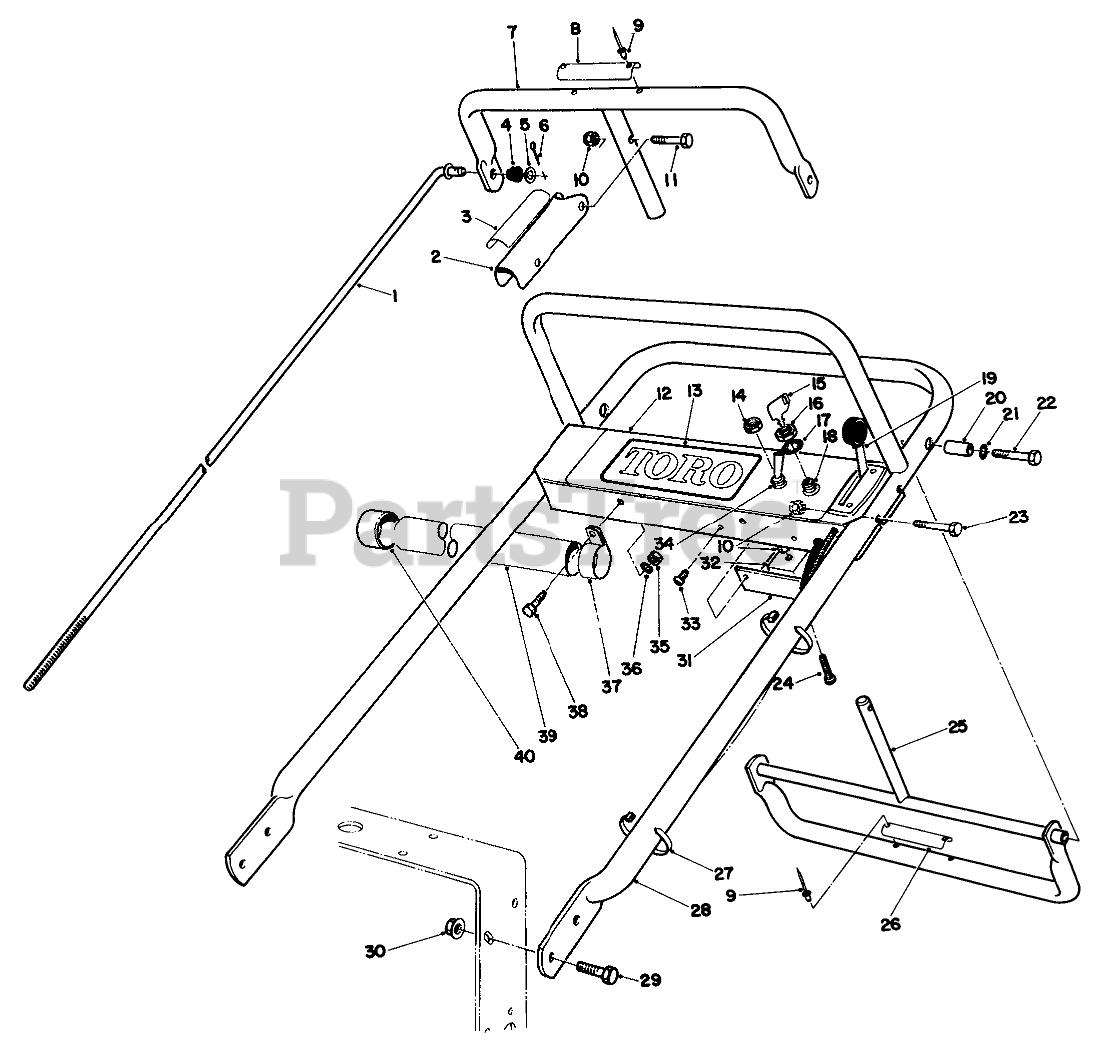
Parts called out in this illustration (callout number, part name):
1	ROD-CONTROL
2	Lever-Parking Brake
3	DECAL-LEVER, PARKING
4	GROMMET-RUBBER
5	WASHER-PLAIN
6	PIN-COTTER
7	Bar-Control
8	DECAL-CONTROL BAR
9	RIVET-BLIND
10	NUT-LOCK, NI
11	SCREW-SHH
12	Panel-Control
13	DECAL-CONTROL PANEL
14	NUT
15	KEY-IGNITION
16	NUT-HH
17	WASHER-TOOTH, INTERNAL
18	Switch (Incl. Ref. #16 & 17)
19	THROTTLE-CONTROL
20	PIVOT-SPACER
21	WASHER-LOCK
22	SCREW-HH
23	SCREW-SHH
24	SCREW-HWH
25	Control-Pivot
26	DECAL-REVERSE HANDLE
27	TIE-CABLE
28	HANDLE-UPPER
29	SCREW-HHF
30	NUT-HF
31	PANEL-BOTTOM
32	RECTIFIER-BRIDGE
33	SCREW-HWHTF
34	Switch-Clutch (Incl. Ref. #14)
35	NUT-LOCK, NI
36	WASHER-FLAT
37	CLAMP-R
38	SCREW-HH
40	CAP-END
